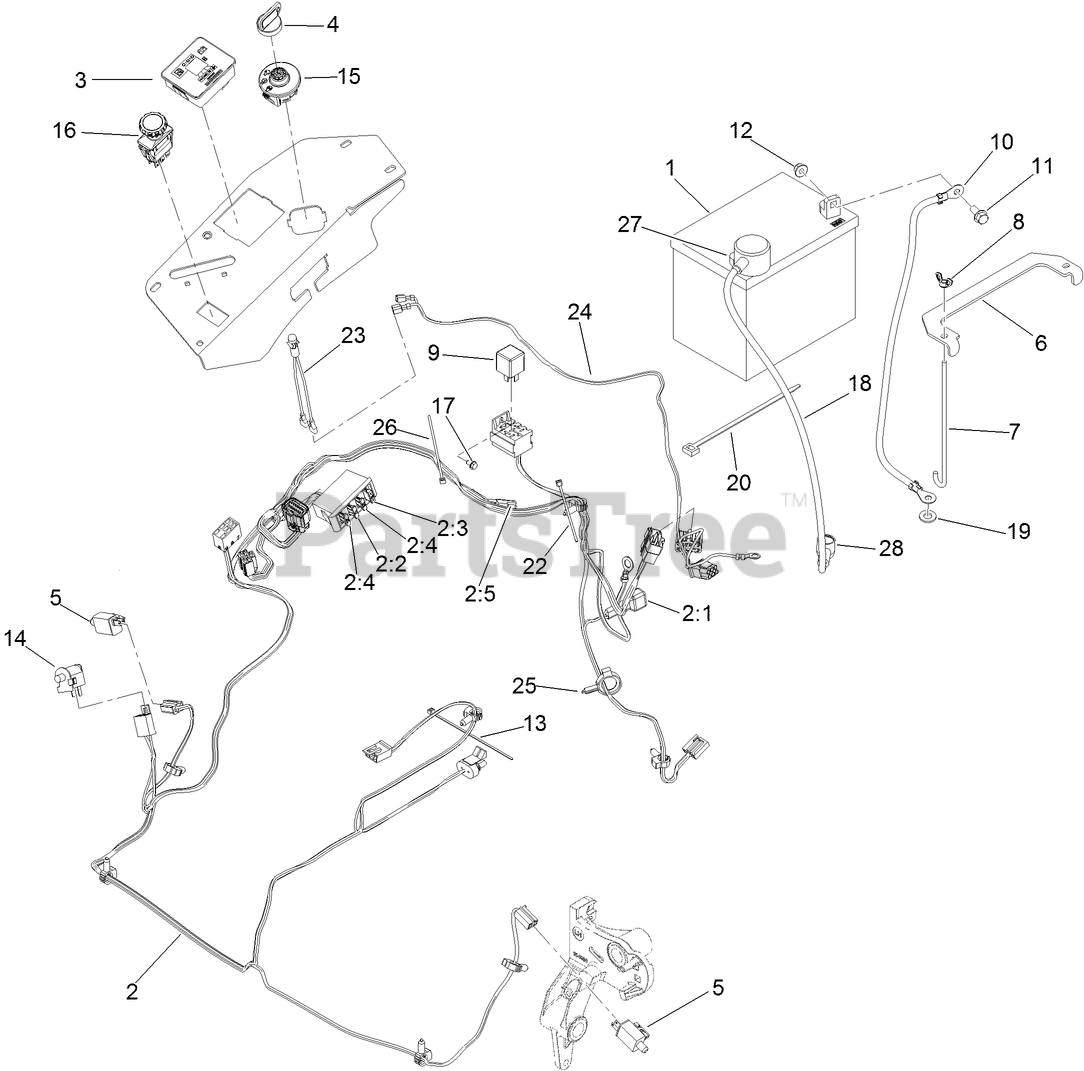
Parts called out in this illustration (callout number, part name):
1	BATTERY-DRY
2	HARNESS-WIRE, MAIN
2:2	FUSE-BLADE, 10 AMP
2:3	FUSE-BLADE, 15 AMP
2:4	FUSE-BLADE, 25 AMP
2:5	CAP-PLUG
3	FUEL/HOUR METER ASM
4	KEY-IGNITION
5	SWITCH
6	STRAP-TIE DOWN, BATTERY
7	BOLT-HOLDDOWN
8	WINGNUT
10	CABLE-BATTERY, NEGATIVE
11	SCREW-HHF
12	NUT-HF, NI
13	TIE-CABLE
14	SWITCH-BAIL
15	SWITCH-IGNITION
16	SWITCH-PTO, 10 AMP
17	SCREW-HWH
18	CABLE-BATTERY, POSITIVE
19	WASHER-FLAT
20	TIE-PLASTIC
22	TIE-PLASTIC
23	INDICATOR-LED, RED
24	HARNESS-LIGHT, INDICATOR
25	CLAMP-HOSE
26	TIE-CABLE
27	INSULATOR-BATTERY
28	INSULATOR-SOLENOID
